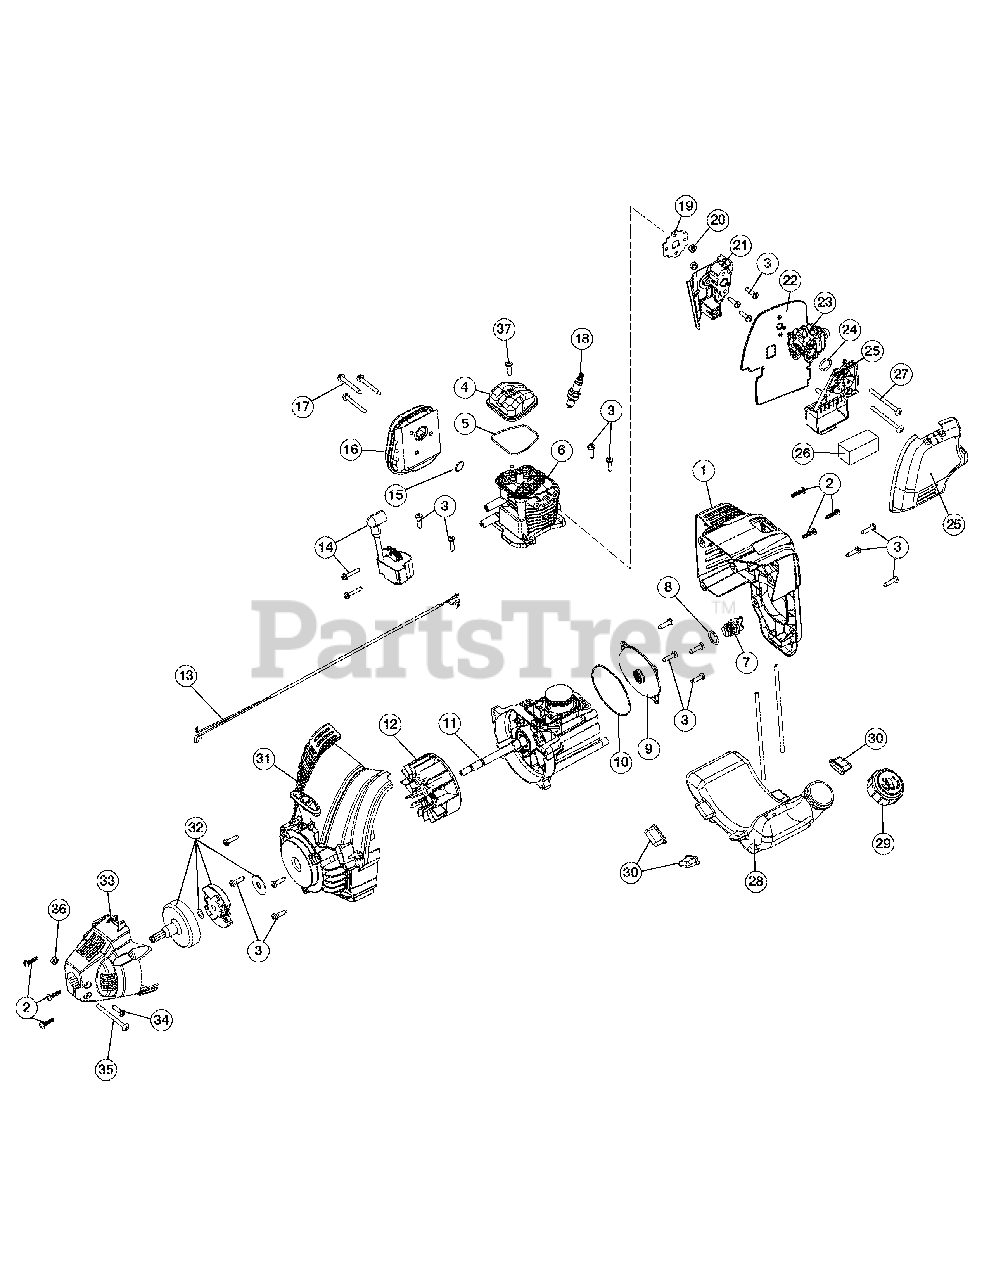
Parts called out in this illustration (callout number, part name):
1	Engine Cover Assembly (Incl. Ref No. 2 & 3)
2	Cover Screw
3	Screw
4	Rocker Cover
5	Rocker Cover O-Ring
6	Cylinder Assembly (Incl. Ref No. 3 & 5)
7	Oil Plug (Incl. Ref No. 8)
8	Oil Plug O-Ring
9	Crankcase Cover
10	Crankcase Cover O-ring
11	Crankcase Assembly (Incl. Ref No. 10)
12	Flywheel Assembly
13	Lead Wires
14	Module Assembly
15	Muffler Gasket
16	Muffler Assembly (Incl. Ref No. 15 & 17)
17	Muffler Screw
18	Spark Plug
19	Insulator Gasket
22	Carburetor Gasket
23	Carburetor
25	Air Cleaner Cover Assembly (Incl. Ref No. 26)
26	Air Filter
28	Fuel Tank Assembly w/Fuel Lines (Incl. Ref No. 29)
30	Fuel Tank Pads
31	Starter Housing Assembly (Incl. Ref No. 3)
32	Clutch Assembly
33	Clutch Cover (Incl. Ref No. 2)
34	Anti-Rotation Screw
35	Clamp Screw
36	Nut
37	Rocker Cover Screw
